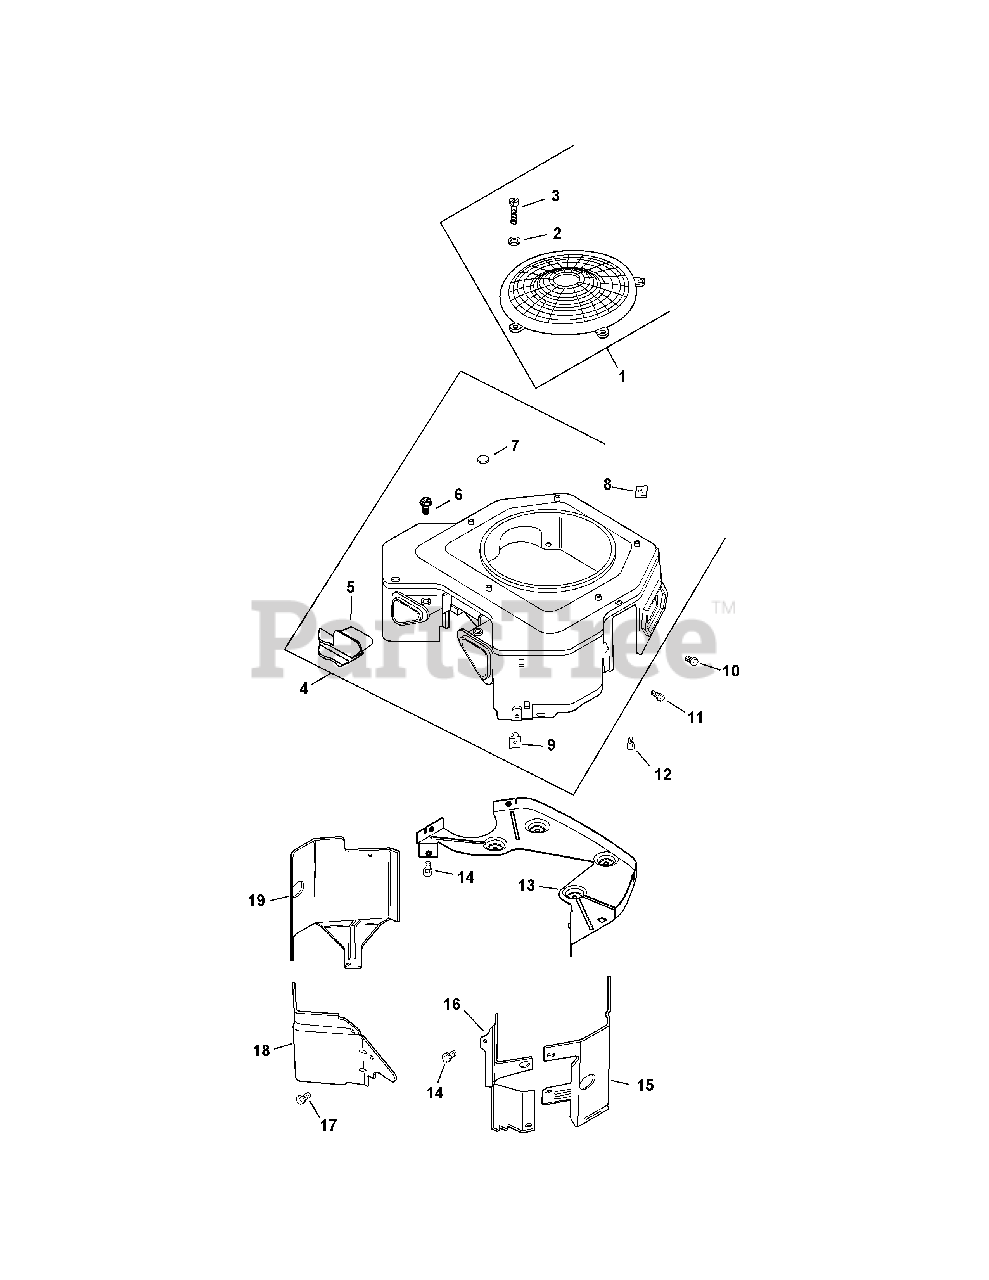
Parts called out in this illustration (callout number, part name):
1	KIT, FIXED GUARD
2	WASHER, FLAT
3	SCREW, PAN HEAD
4	BLOWER HOUSING ASSEMBLY
5	COVER, BLOWER HOUSING-MOLDED
6	SCREW, TAPPING #10-16x1/2
7	PLUG, BUTTON 9/16
9	PLASTIC NUT USE 25 100 37-S
10	SCREW, FLG THD FRM M5X.8X16
11	SCREW, FLG THD FRM M5X0.8X16
12	SCREW, FLG THD FRM M5X.8X20
13	BACKING PLATE USE 24 146 59-S
14	SCREW, FLG THD FRM M6X1.0X16
15	KIT, CYL BAFFEL #2 SIDE
16	BAFFLE, VALLEY #2 CYLINDER
17	SCREW, FLG THD FRM M5X.8X10
18	BAFFLE, VALLEY #1 CYLINDER
19	KIT, CYL BAFFEL #1 SIDE
